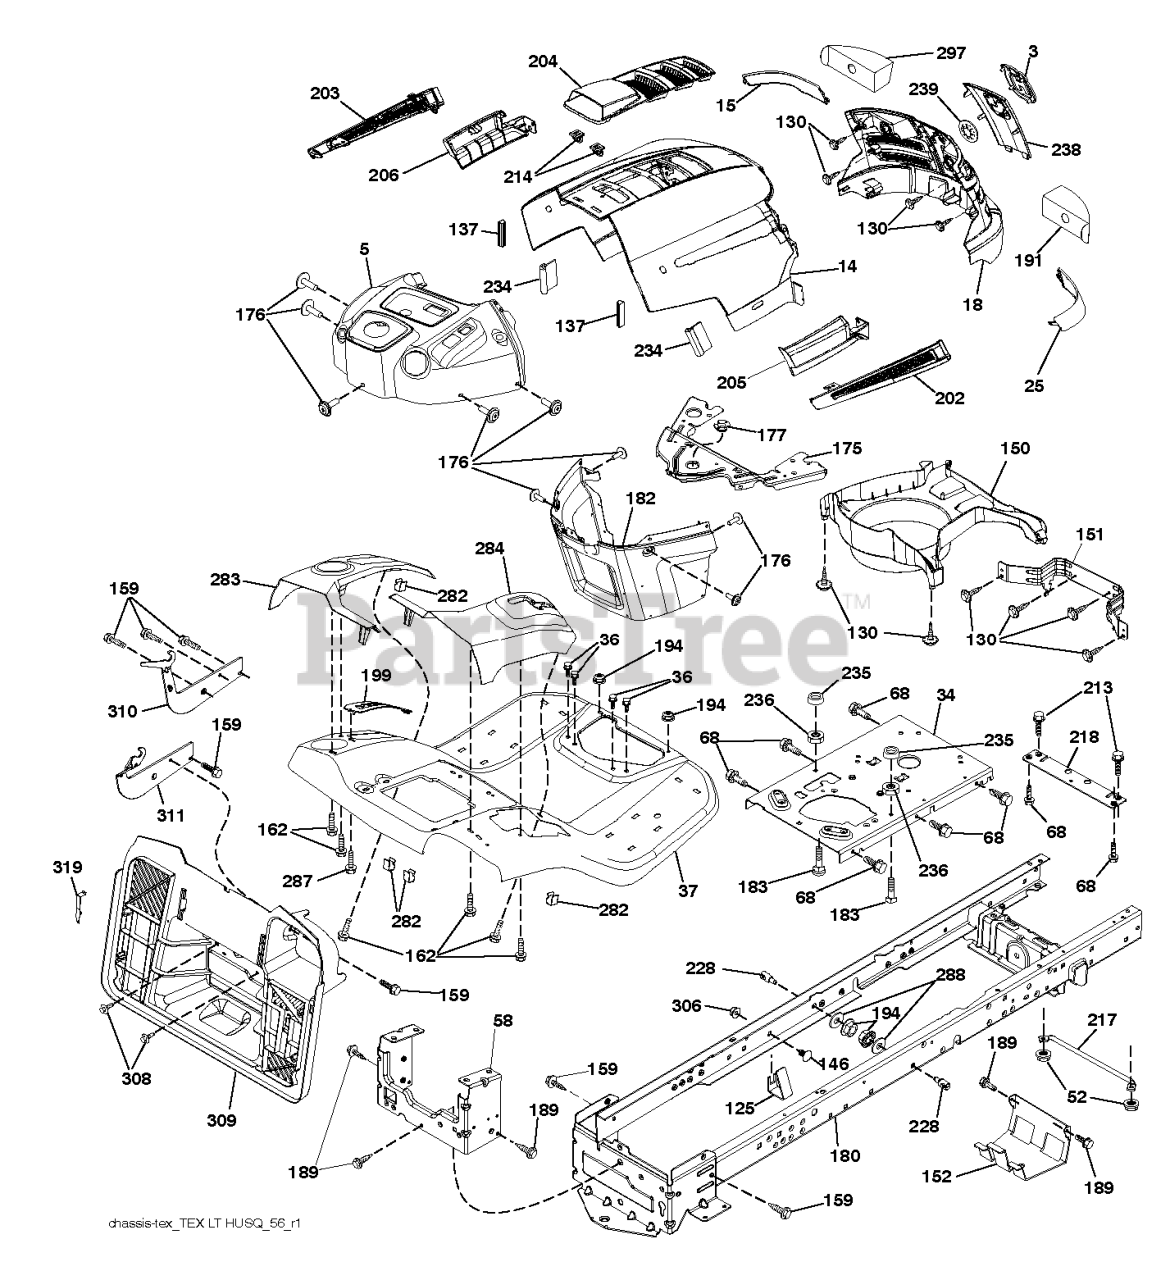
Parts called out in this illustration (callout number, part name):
3	LOGO.HUSQ.GT.LT.CROWN.H
5	SUBASM.DASH.UPPER.HLT.498
14	HOOD.HUSQVARNA.LT.ORANGE
15	LENS.HUSQVARNA LT.RH
18	GRILLE.SVC.HUSQVARNA.GREY
25	LENS.HUSQVARNA LT.RH
34	PLATE PLATE ENGINE
36	SCREW 5/16"
37	FENDER.TEX.SRD.CRD.BASE
52	LOCKNUT
58	DRAWBAR UPPER 2PC SMALL FENDER
68	Screw 5/16-18 x 1/2 Hex, Self Tapping 5/16-18 x 1/2
125	CLIP.FUEL.LINE
130	SCREW.#10 X 0.750.BOS
137	BUMPER DASH
146	BOLT.RDHD.SHT.SQNK.3/8-16X5/8
151	BRACKET PIVOT
152	SHIELD.BROWNING.W/TEX
159	SCREW, 3/8-16X3/4
162	SCREW.HI-LO.CONSOLE
175	CROSSMEMBER
176	SCREW.#10-24X5/8.RN.QU
177	BUSHING STEERING
180	CHASSIS.WLDMNT.14GA.2PC.18".TI
182	DASH.LOWER.PREDATOR LT
183	BOLT.5/16-18X1-1/4 FULL THD
189	SCREW
191	INSERT.REFLECTIVE.RH.
194	NUT LOCK HEX FLANGE 5/16-18
199	PLATE DECK LIFT
202	VENT.SIDE.HUSQVARNA.LT.RT
203	VENT.SIDE.HUSQVARNA.LT.LFT
204	SUBASM.TOP.VENT.HUSQ.LT
205	SKIRT.SIDE.HUSQVARNA.LT.RT
206	SKIRT.SIDE.HUSQVARNA.LT.LEFT
213	BOLT
214	CLIP.RETAINER.TINNER.
217	ROD.PIVOT.HOOD
218	X-PIECE.HOOD.STOP.NON/
228	STUD.FASTNER.W/ANTI-ROTATE
234	BUMPER.HOOD.TEX.HUSQVARNA
235	SPACER FENDER
236	NUT.CENTERLOCK.5/16-
238	TRIM.HUSQ LT.668
282	CLIP.RETAINER.CONSOLE.LT.HUSQ
283	CONSL.DECKLIFT.LH.SRD.TEX.CRD
284	CONSL.SHFT.PEDAL.RH.SRD.TEXCRD
287	SCREW 1/4X20
288	WASHER
297	INSERT REFLECTIVE
306	NUT LOCK FLG 3/8-16 UNC
308	BOLT.5/16-18UNCX3/4 W/SEMS.BLK
309	BACKPLATE.BAGGER.V2.SRD
310	LH.ADJUST.HANGER.BRACKET.ASM
311	RH.ADJUST.HANGER.BRACKET.ASM
319	BRACKET.ACTUATOR.BAGGER.SRD
